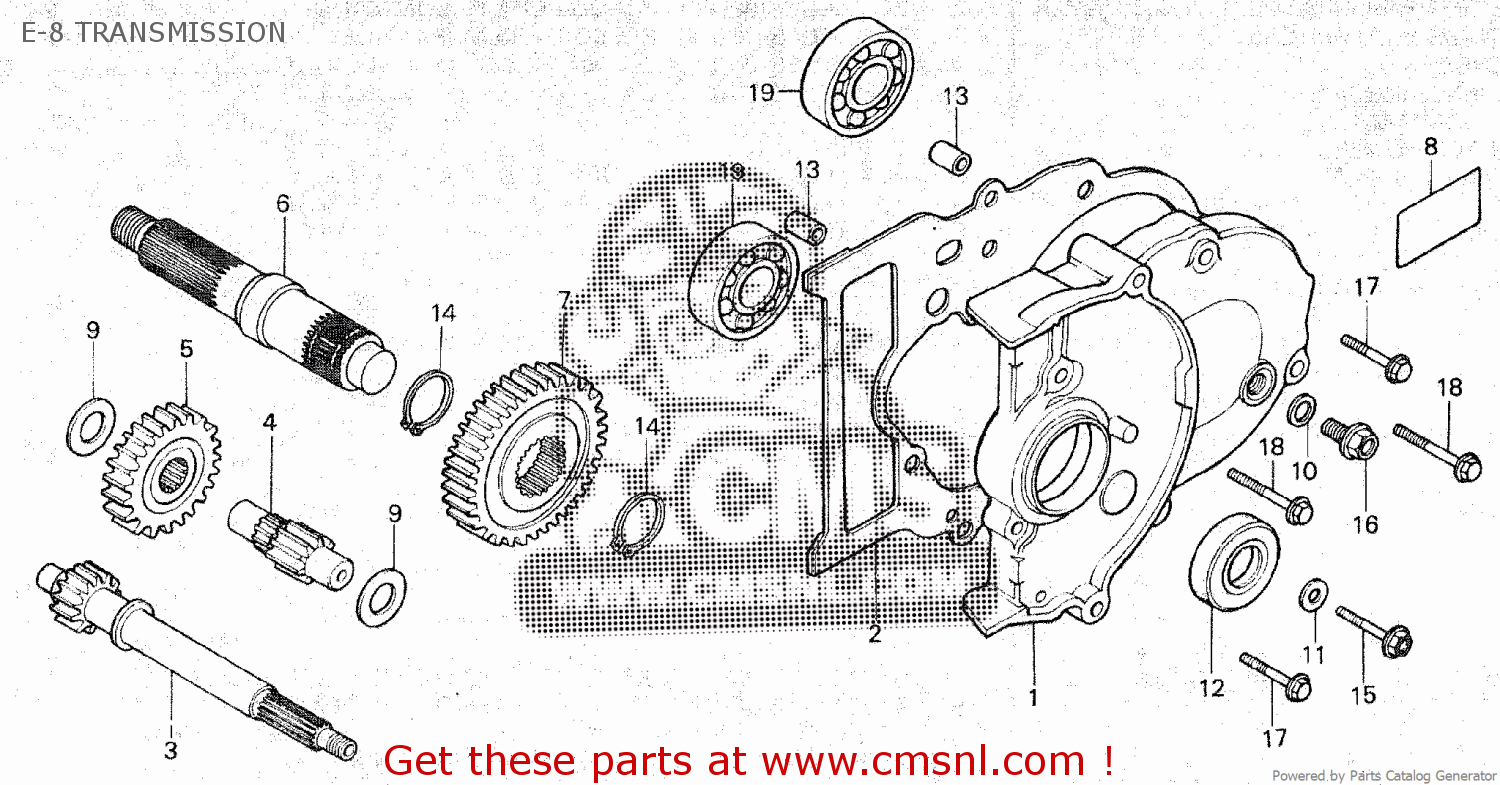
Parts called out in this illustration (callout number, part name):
1	COVER,MISSION
2	GSKT,MISSION COV. (MCA)
3	SHAFT,DRIVE
4	SHAFT,COUNTER
5	GEAR,COUNTER
6	SHAFT,FINAL
7	GEAR,FINAL
8	LABEL, OIL CAPACITY
9	WASHER,14MM
10	WASHER, 10.2M/M
11	WASHER A, 6.5M/M
12	OIL SEAL,15X30X5
13	DOWEL PIN
14	CIRCLIP, 22M/M
15	BOLT,FLANGE, 6X32
16	BOLT,FLANGE,10X12
17	BOLT,FLANGE,6X28
18	BOLT,FLANGE,6X35
19	B/BRG RAD N/COM
